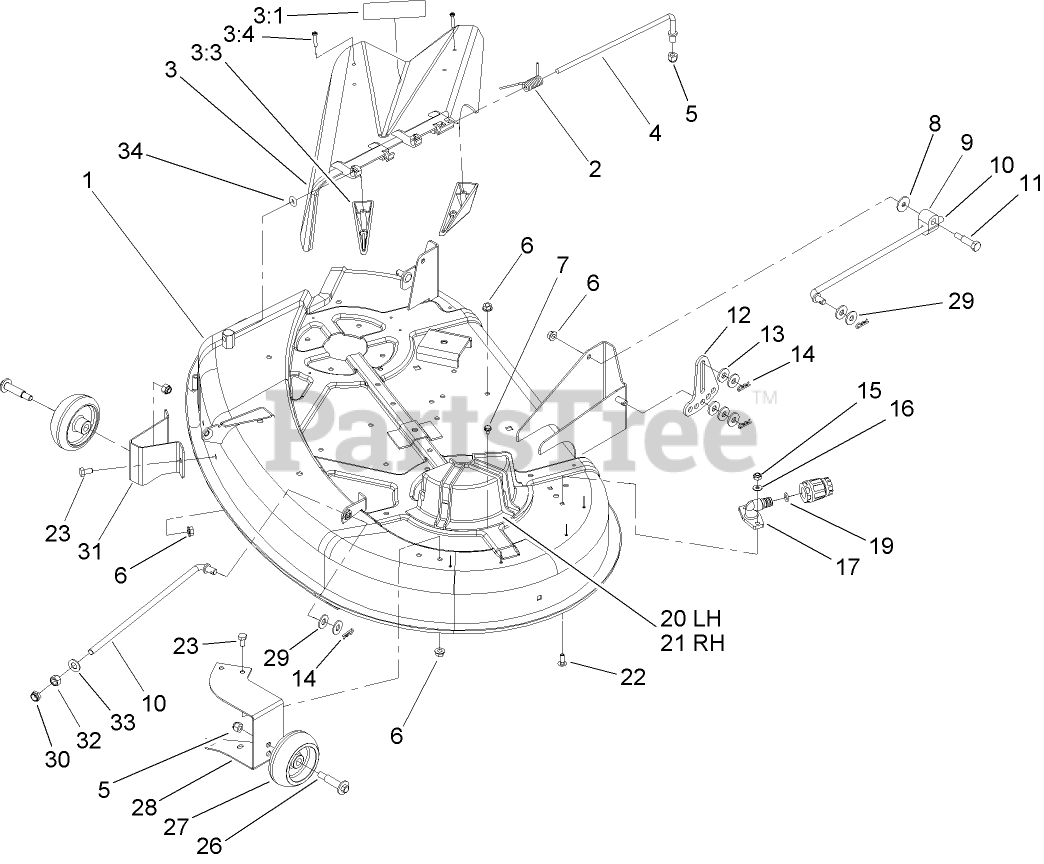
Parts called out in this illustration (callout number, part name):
1	38 INCH DECK ASM
2	SPRING
3	DEFLECTOR ASM
3:1	DECAL-DANGER
3:3	KICKER
3:4	SCREW-PPH
4	ROD-PIVOT
5	NUT-LOCK, NI
6	NUT-HF
7	SCREW-HWHTF
8	WASHER-PIVOT
9	TRUNNION-HOC
10	ROD-HANGER
11	SCREW-SHOULDER, HH
12	LINK-ADJUSTING, HOC
13	WASHER-HARDENED
14	PIN-HAIR
15	NUT-LOCK, NI
16	WASHER-FLAT
19	O-RING
20	GUIDE-BELT, LH
21	GUIDE-BELT, RH
22	BOLT-CARR
23	SCREW-HH
26	SCREW-SHOULDER, HWH
27	WHEEL-GAGE
28	BRACKET-WHEEL, GAGE (FRONT, LH)
29	WASHER-FLAT
30	NUT-LOCK, NI
31	BRACKET-WHEEL, GAGE (FRONT, RH)
32	NUT-HEX
33	WASHER-FLAT
34	O-RING
